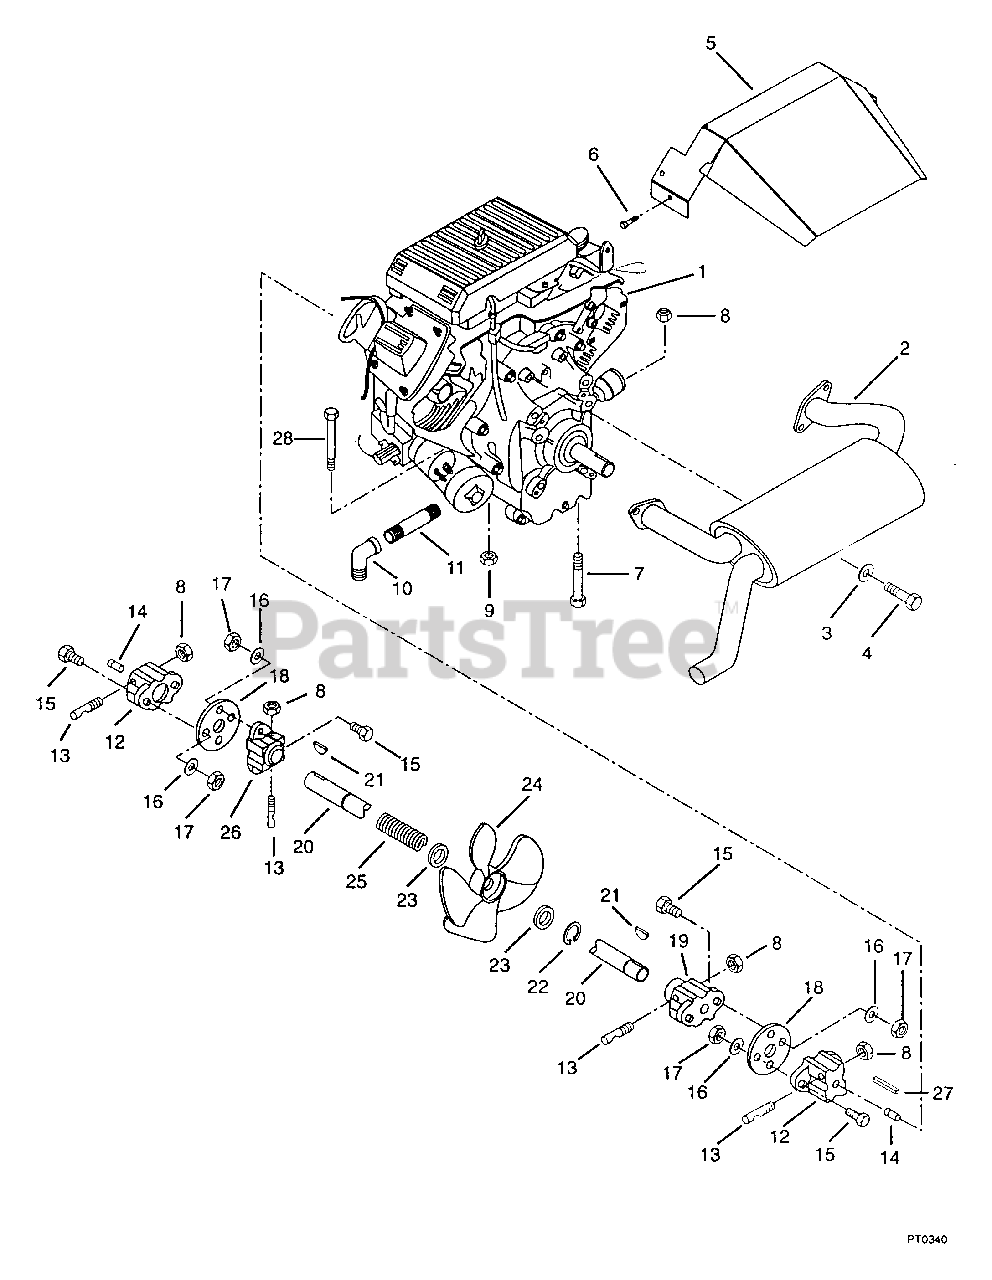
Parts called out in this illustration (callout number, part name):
1	KOHLER 22HP COMMAND OHV TWIN
2	MUFFLER - NELSON
3	WSHR-LK .438X.133 HVY
4	BLT-HEX .44-14X1.00 GR5
5	SHIELD, HEAT
6	BLT-HEX M6 X 1.0X12 LG
7	BLT-HEX .38-16X1.75 PL GR5
8	NUT-LK TOP .375-16 GR C YWZC
9	NUT-LK-CTR .375-16 GR A PL
10	ELBOW .375-18 NPTF
12	DRIVE HUB
13	LOCK STUD
14	PIN-GRV .313X.75 TP D
15	BLT-HEX .31-18X.88 PL GR2
16	WSHR-FL-STL.344X.688X.065PL
17	NUT-LK .312-18 GR A PL
18	SPACER COUPLING
19	DRIVE HUB- TWIN SHAFT
20	SHAFT, DRIVE
21	KEY-WDRF .188X.75X.313 SAE 9
22	RG-RTNG-EXT .750X.042
23	WSHR-HDND-THRST .758X1.23X.031
25	SG-COMP .120X.75X2.50 WLD48
26	DRIVE HUB
27	KEY-SQ .188X.75X.188
28	BLT-HEX .38-16X1.50 PL GR5
